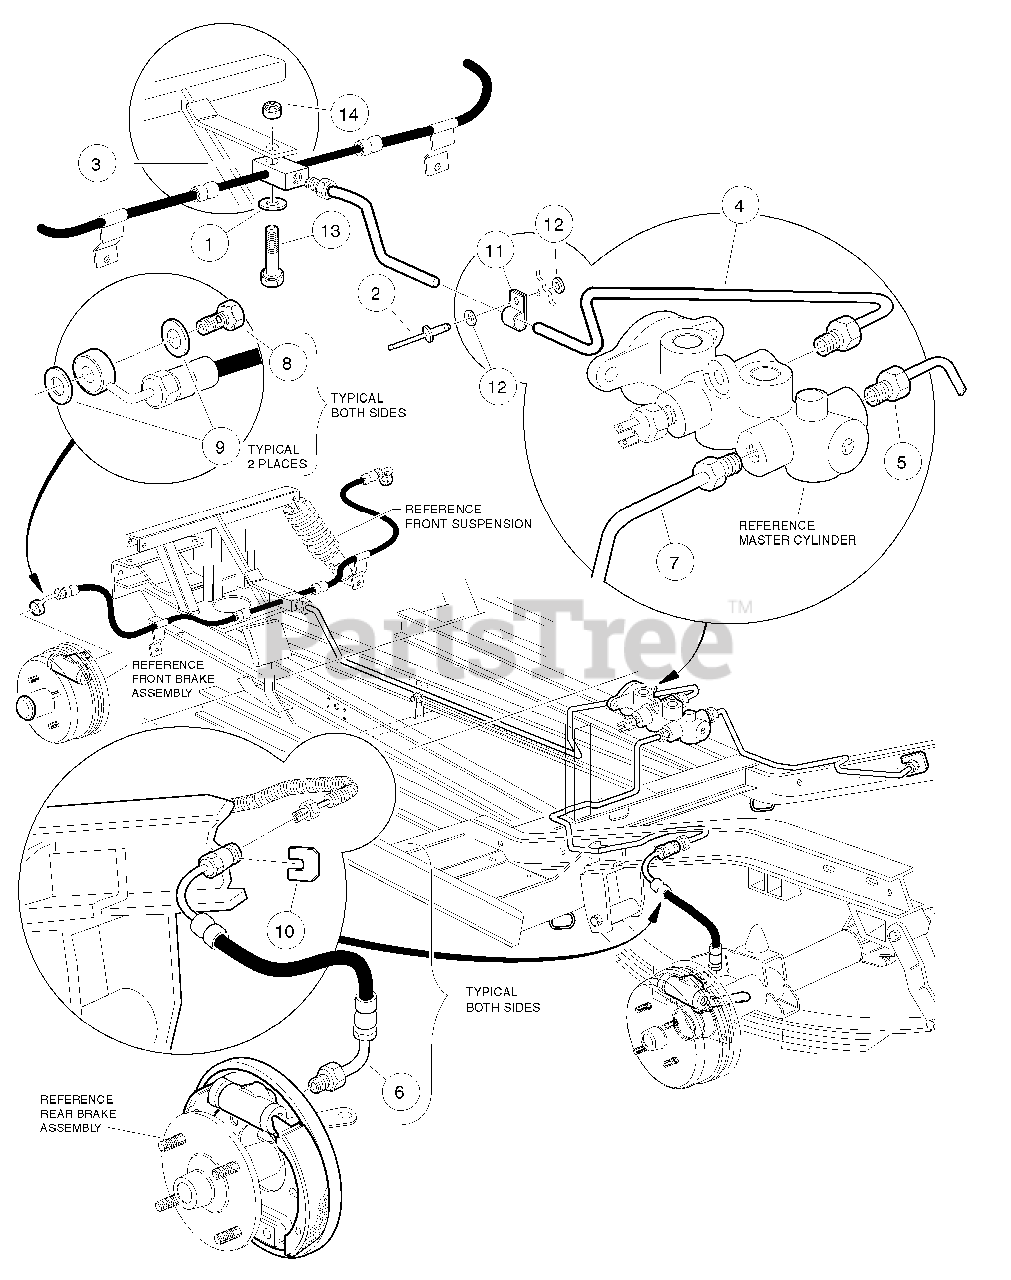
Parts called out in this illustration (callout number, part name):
1	Washer, 1/4 Flat
2	Rivet, 3/16 Diameter Drive
3	Hose, Hydraulic, Front Brake
4	Line, Hydraulic Rear Brake Front
5	Line, Hydraulic Rear Brake, Right-Hand
6	Hose Flex Rear
7	Line Hyd Rear Brake LS
8	Bolt, Banjo
9	Copper Washer
10	Horse Shoe Clamp
12	Washer, #10 Type A Flat
13	Screw, 1/4-20 X 125 Hex-Head Cap
14	Locknut, 1/4-20 Nylon Insert
